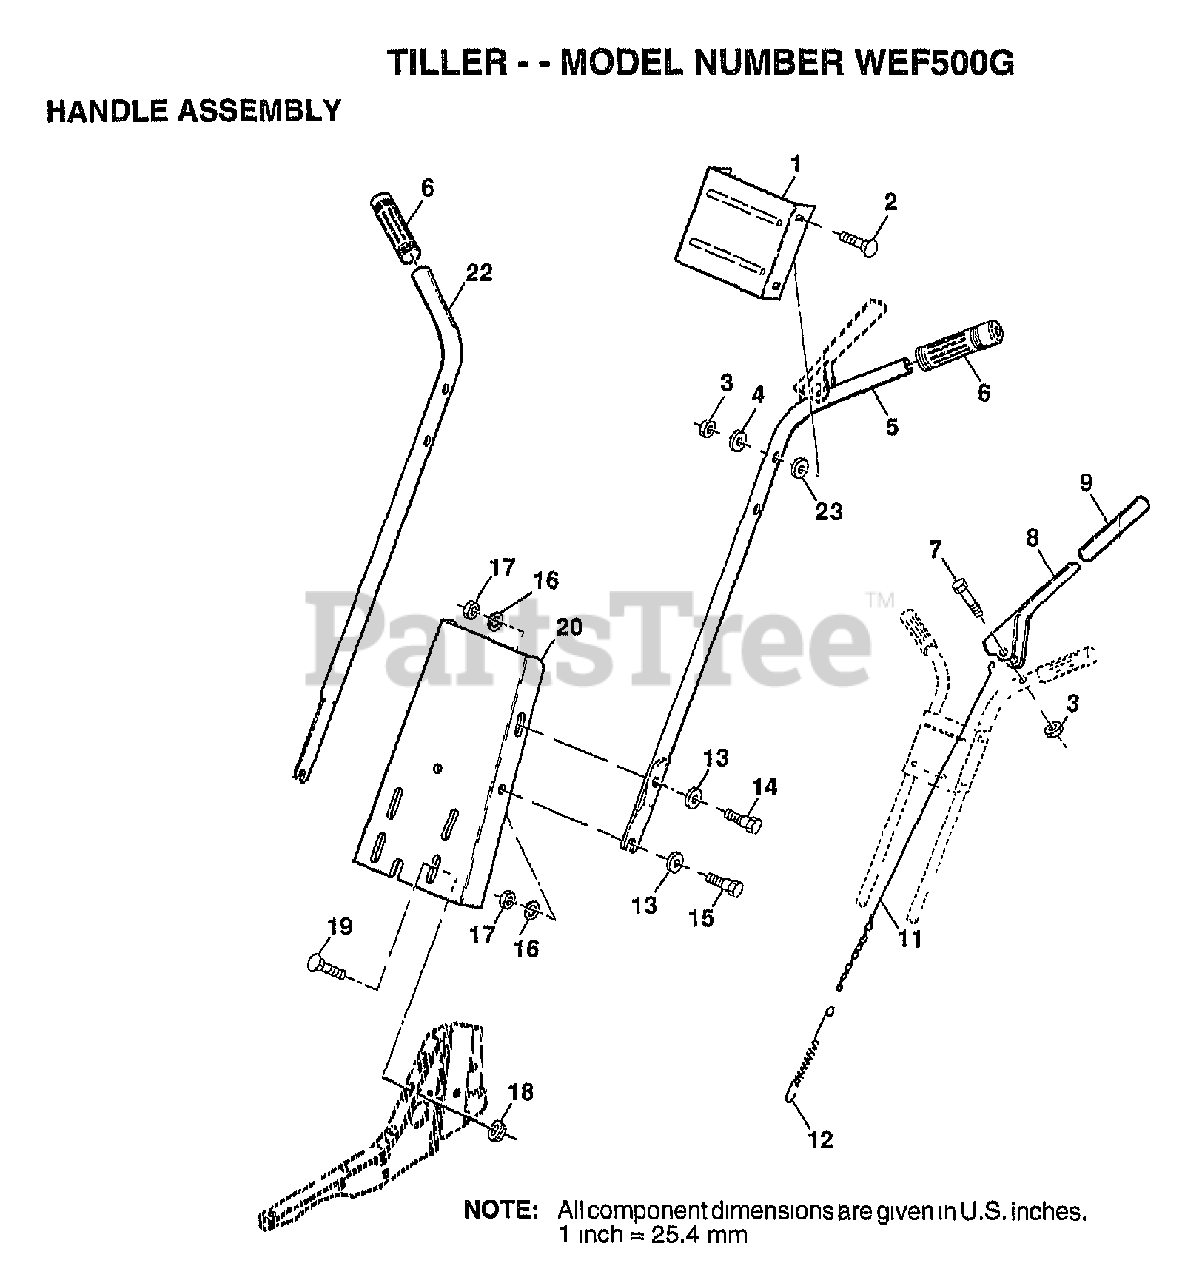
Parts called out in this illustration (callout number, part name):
1	PANEL.CNTRL.HDLE.
2	BOLT
4	WASHER
5	HANDLE LH
7	BOLT.HEX.5/16-1.5
8	LEVER.CONTROL.TINE
9	GRIP T
12	SPRING EXT TI
13	WASHER
15	BOLT
16	LOCKWASHER
17	NUT.HEX.5/16-18
18	NUT
19	BOLT
20	PANEL.HANDLE.TILL
22	HANDLE RH
23	WASHER
